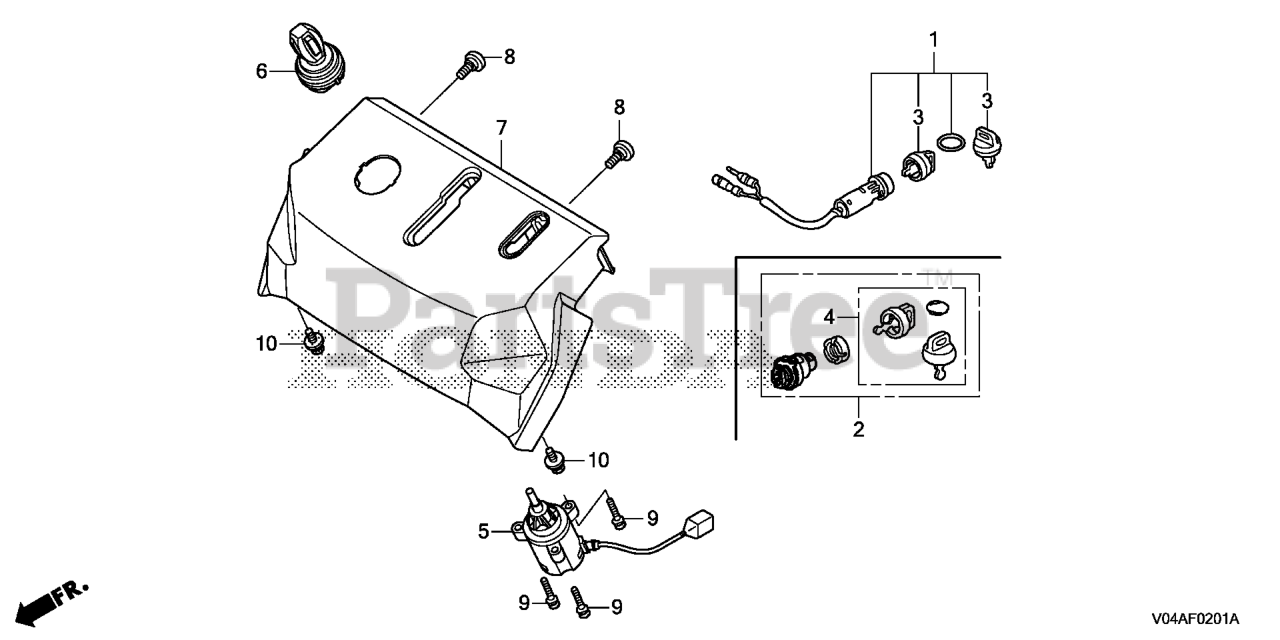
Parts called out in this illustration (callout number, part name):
1	SWITCH ASSY., COMBINATION
3	KEY ASSY., COMBINATION SWITCH (RED)
5	SW CHUTE CNTRL
6	BOOT, RUBBER
7	PANEL, CONTROL *NH296* (ALPS GRAY)
8	BOLT, CHUTE SETTING
9	BOLT-WASHER (5X20)
10	BOLT-WASHER (5X12)
